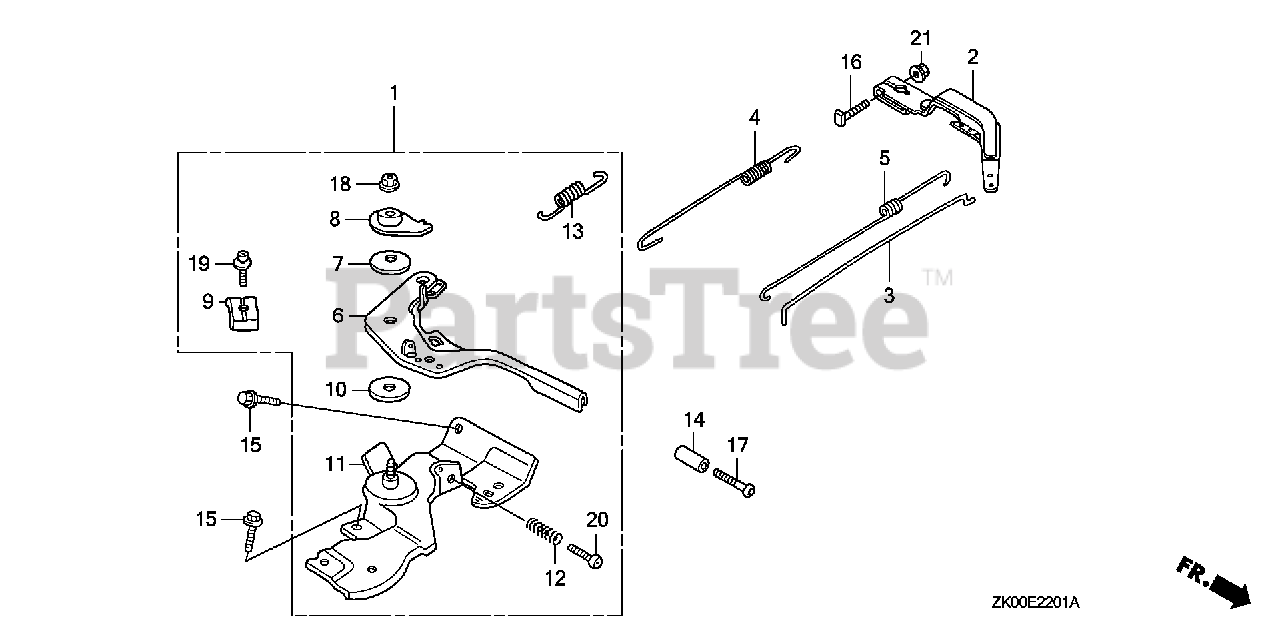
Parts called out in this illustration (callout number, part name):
1	CONTROL ASSY. (REMOTE)
2	ARM, GOVERNOR
3	ROD, GOVERNOR
4	SPRING, GOVERNOR
5	SPRING, THROTTLE RETURN
6	LEVER, CONTROL
7	SPRING, LEVER
8	WASHER, CONTROL LEVER
9	HOLDER, CABLE
10	SPACER, CONTROL LEVER
11	BASE, CONTROL (REMOTE)
12	SPRING, CONTROL ADJUSTING
13	SPRING, CABLE RETURN
15	BOLT, FLANGE (6X12) (CT200)
16	BOLT, GOVERNOR ARM
18	NUT, SELF-LOCK (6MM)
19	SCREW, PAN (5X16)
20	SCREW, PAN (5X25)
21	NUT, FLANGE (6MM)
